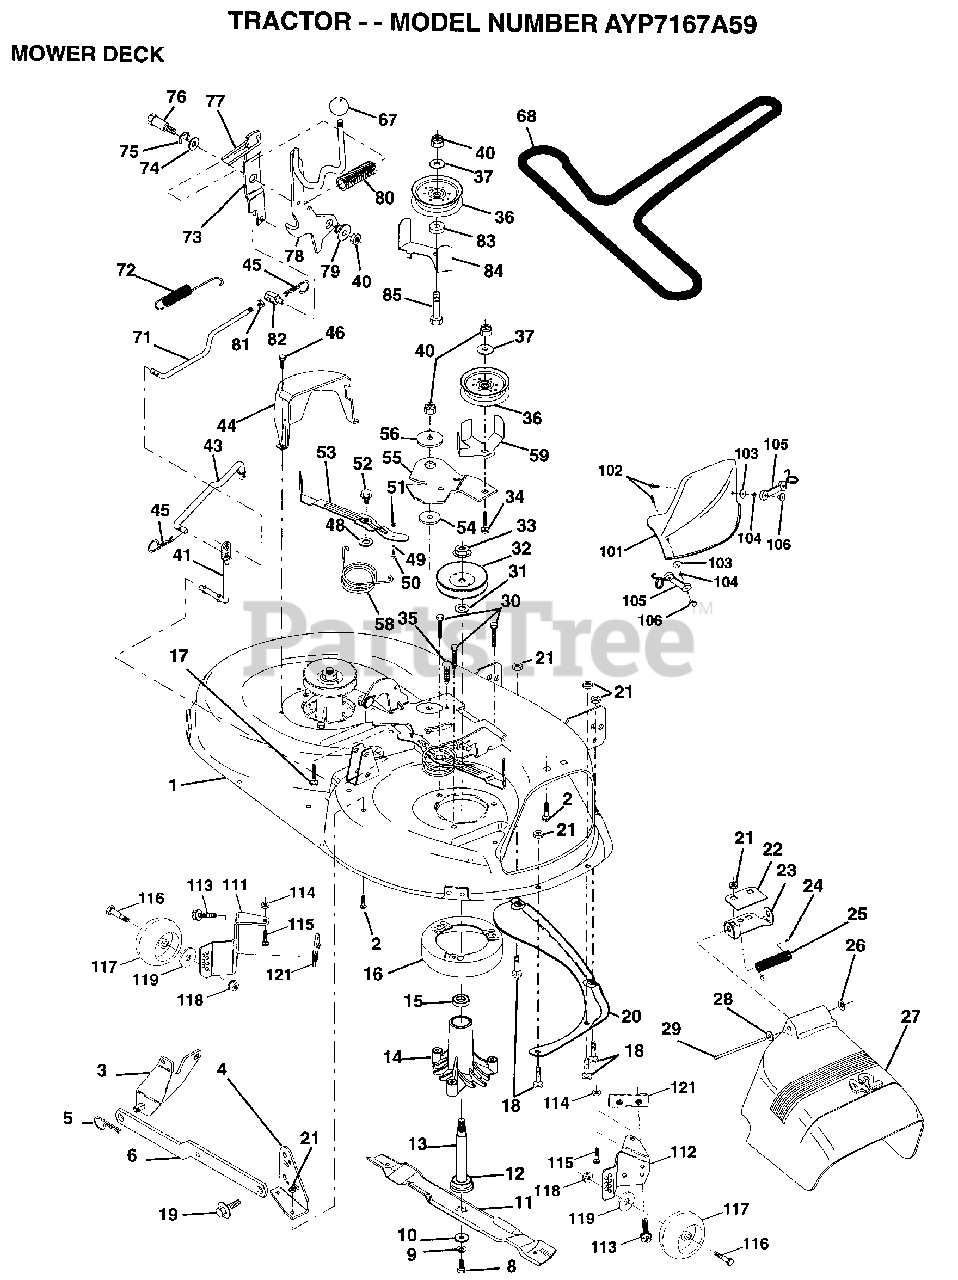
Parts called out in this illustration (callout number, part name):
1	DECK.WELD.42.
2	BOLT
3	BRKT ASM SWAY BAR
4	BRKT DECK SW BAR
8	BLADE BOLT
10	WASHER.HARD.BLADE
11	"BLADE.42"" MULCHER"
12	BEARING.BALL
14	HSG ASM MANDREL
15	BEARING
16	STRIPPER RND MWR
17	BOLT RDHD 3/8-16
18	BOLT
19	BOLT SHD 5/16-18
22	STIFFENER BRKT
23	DEFLECTOR BRKT
24	CAP-SLEEVE LT
25	SPRING TORSION
26	NUT PUSH M
27	DEFLECTOR.SHIELD
28	WASHER
29	HINGE ROD
31	WASHER
34	BOLT
35	XMAS TREE FASTNER
36	FLAT IDLER PULLEY
37	WASHER
41	PIVOT ROD
43	ROD CLUTCH W/NIBS
44	GUARD MAND LH BLK
45	RETAINER M
46	SCREW.1/4-20X5/8
48	HARD SMALL WASHER
50	SHOULDER BOLT
51	LOCKNUT
52	BOLT.SHLD.5/16-18
53	BRAKE PAD ARM ASM
54	HARDENED WASHER
56	SPACER RETAINER
58	SPRING TORSN BRAK
59	GUARD IDLER TUV
67	KNOB T (1/2-HOLE)
68	BELT.V.T-PATH
71	ROD CLUTCH 38/42
72	RETURN SPRING
73	CLUTCH ARM SECOND
74	WASHER
75	RING
76	SHOULDER BOLT
77	SPRING KEEPER
78	LEVER ASM CLT PRM
79	BUSHING
81	NUT
82	TRUNION ADJ
83	WASHER
85	BOLT
101	"COVER.MULCH.42"""
102	SCREW
103	WASHER #10
104	LOCKWASHER
106	WELDNUT
113	SCREW
116	BOLT.SHOULDER
117	WHEEL GAGE DONUT
118	LOCKNUT
119	WASHER
121	BRACKET.EXTRD.GWL
